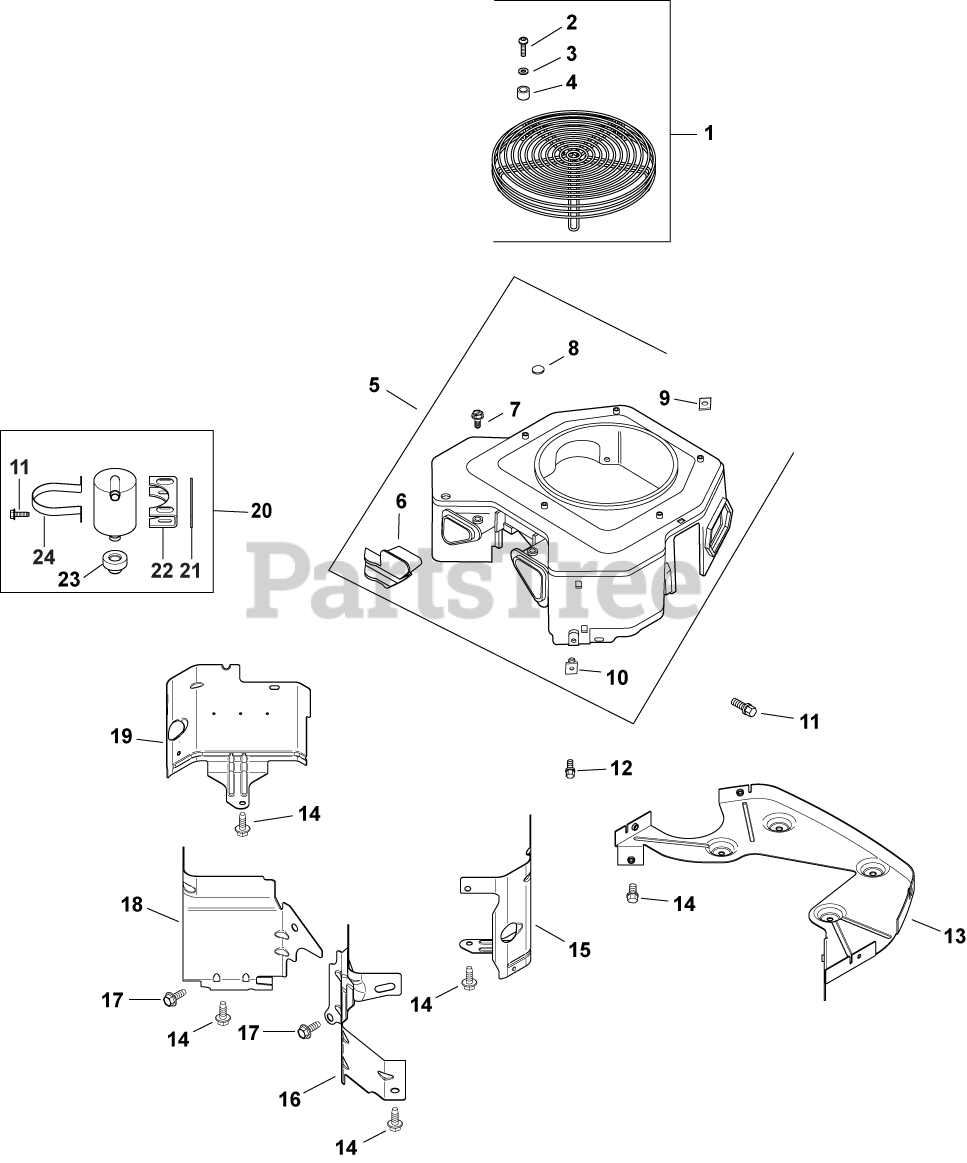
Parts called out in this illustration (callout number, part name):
5	BAFFLE, VALLEY #1 CYLINDER
6	KIT, CYL BAFFEL #2 SIDE
10	NUT, PLASTIC
12	KIT, CYL BAFFEL #1 SIDE
14	BAFFLE, VALLEY #2 CYLINDER
15	KIT, BACKING PLATE
22	COVER, BLOWER HOUSING USE 24 096 160-S
23	SCREW, THREAD FORMING
24	SCREW, THREAD FORMING
25	SPACER USE 25 112 30-S
26	KIT, GUARD
27	INSERT, THREADED USE 25 332 19-S
28	SCREW, SEMS
30	SCREW, THREAD FORMING
31	SCREW, THREAD FORMING
32	HOUSING, BLOWER
